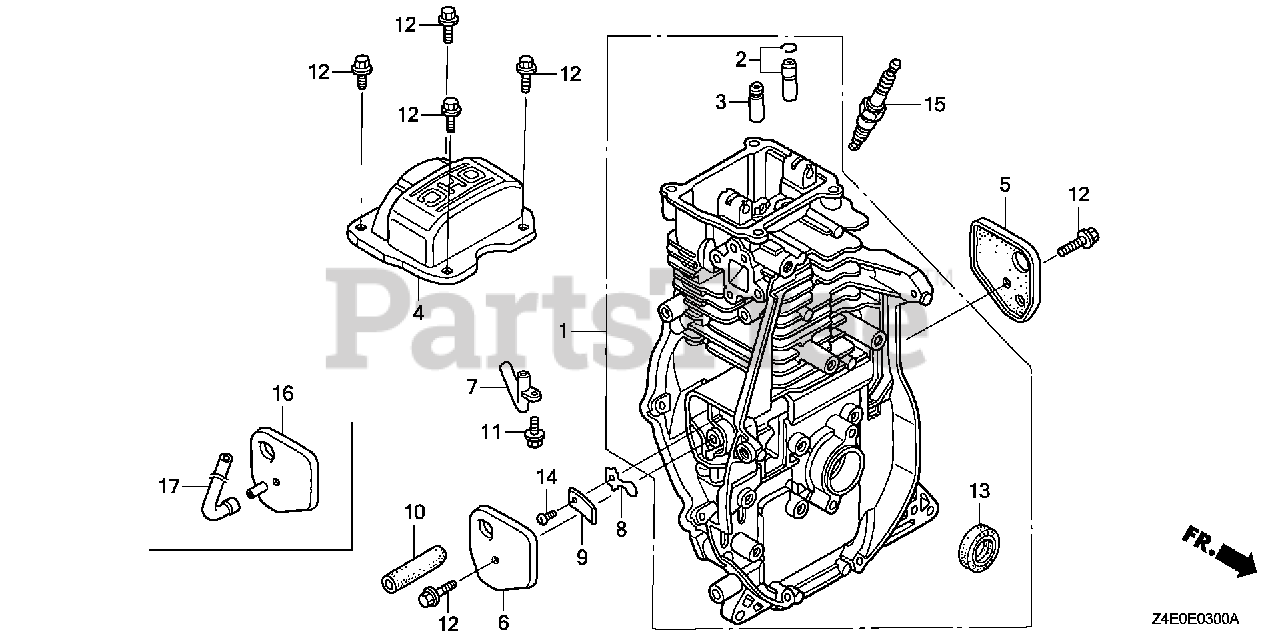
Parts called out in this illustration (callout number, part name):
1	CYLINDER ASSY.
2	GUIDE ASSY., EX. VALVE (OVER SIZE)
3	GUIDE, VALVE (OVER SIZE)
4	COVER, HEAD
5	COVER A, BREATHER
7	PIPE, BREATHER
8	VALVE, OIL OUTLET
9	PLATE, STOPPER
10	TUBE, BREATHER
11	BOLT (4X10)
12	BOLT, FLANGE (6X14) (CT200)
13	OIL SEAL (20X32X6)
14	SCREW, PAN (3X5)
15	SPARK PLUG (CR5HSB)
16	COVER B, BREATHER
17	TUBE, DIAPHRAGM
